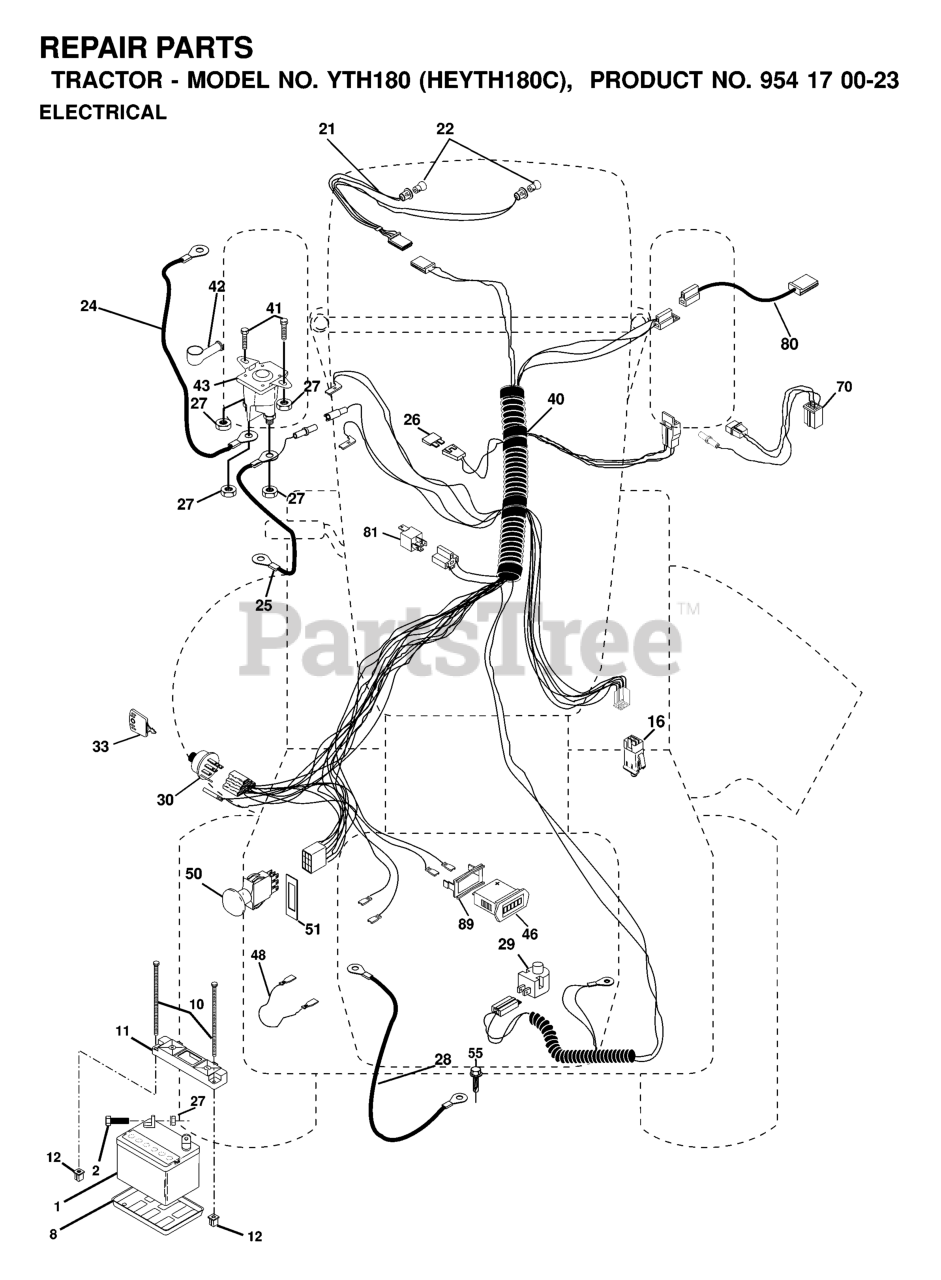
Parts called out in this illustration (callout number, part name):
1	Battery 12 Volt 25 Amp
2	BOLT.HEX.1/4.X.3/4.DICHROMATE
8	BATTERY TRAY T
10	BOLT 1/4-20 X 7.5
11	BATTERY HOLDDOWN FRONT MOUNT
12	NUT, PUSH NYLON 1/4" BATTERY
16	SWITCH INTERLOCK
20	NUT
24	BATTERY CABLE GT
25	CABLE BATTERY 6 GA 22" W/16W
26	FUSE 15 AMP
27	NUT
28	CABLE GROUND 6 GA 21" 90T BLK
29	PLUNGER SWITCH (COLOR:OLIVE)
30	SWITCH IGN
33	KEY MLD GEN DELTA
40	HARNESS IGN.
41	BOLT
42	TERMINAL COVER
43	SOLINOID
46	HOUR METER
48	ADAPTER.AMMETER
50	PTO SWITCH
51	FRAME RETAINING RING
55	Screw 5/16-18 x 1/2 Hex, Self Tapping 5/16-18 x 1/2
80	HARNESS, CLUTCH
81	RELAY.ASSY.T
89	BRACKET SNAP-IN HOURMETER
